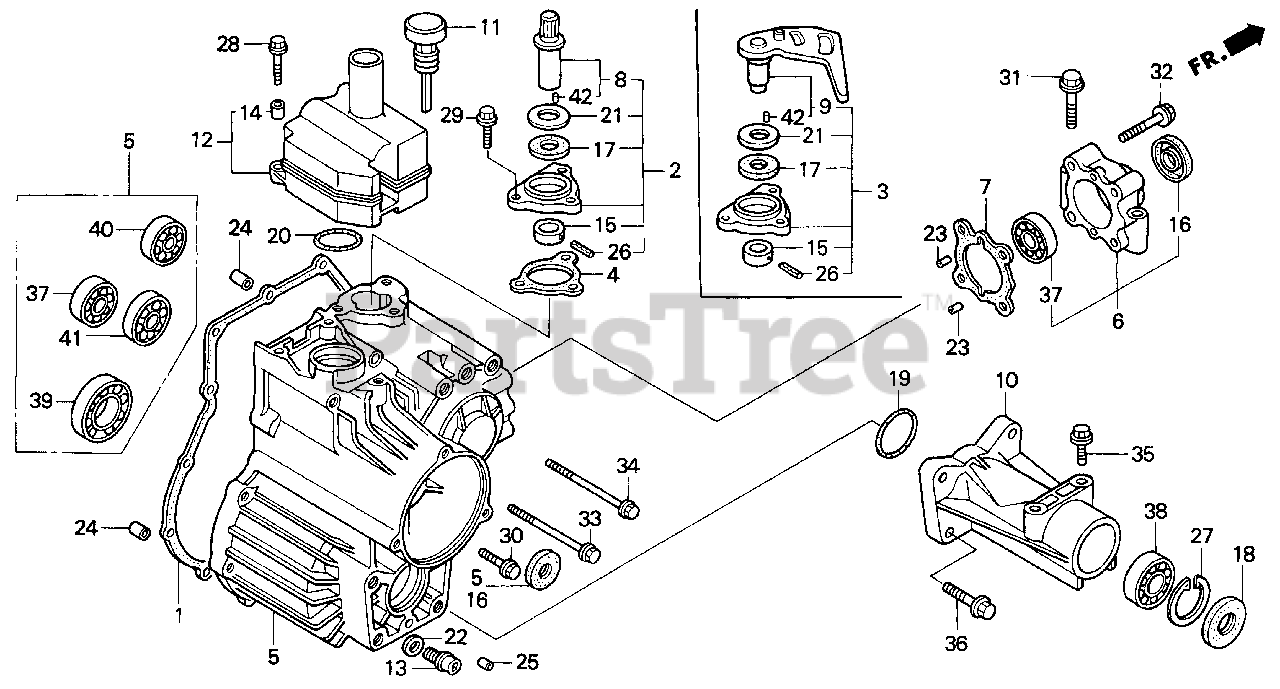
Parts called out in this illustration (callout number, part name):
1	GASKET, L. TRANSMISSION CASE
3	COVER, CONTROL SHAFT
4	GASKET, CONTROL SHAFT COVER
5	CASE, L. TRANSMISSION
6	HOLDER, INPUT SHAFT
7	GASKET, INPUT SHAFT HOLDER
9	SHAFT, CONTROL
10	HOUSING, RR. AXLE
11	CAP, OIL TANK
13	BOLT, PLUG (14MM)
14	COLLAR (6.5X5X14)
15	COLLAR, CONTROL SHAFT
16	OIL SEAL (20X38X8)
17	OIL SEAL (20X30X5)
18	OIL SEAL (25X52X7)
19	O-RING (40.9X2.1) (NOK)
20	O-RING (36X3.2)
21	WASHER, PLAIN (20MM)
22	WASHER, DRAIN PLUG (14MM)
23	PIN A, DOWEL (6X10)
24	PIN A, DOWEL (10X20)
25	PIN, DOWEL (6X10)
26	PIN, SPRING (4X28)
27	CIRCLIP (INNER) (52MM)
28	BOLT, FLANGE (6X28)
29	BOLT, FLANGE (8X25)
30	BOLT, FLANGE (8X35)
31	BOLT, FLANGE (8X40)
32	BOLT, FLANGE (8X50)
33	BOLT, FLANGE (8X105)
34	BOLT, FLANGE (8X110)
35	BOLT, FLANGE (10X25)
36	BOLT, FLANGE (10X40)
37	BEARING, RADIAL BALL (6204)
38	BEARING, RADIAL BALL (6205)
39	BEARING, RADIAL BALL (6206)
40	BEARING, RADIAL BALL (6302)
41	BEARING, RADIAL BALL (6304)
42	ROLLER (6X18) (NOT AVAILABLE)
